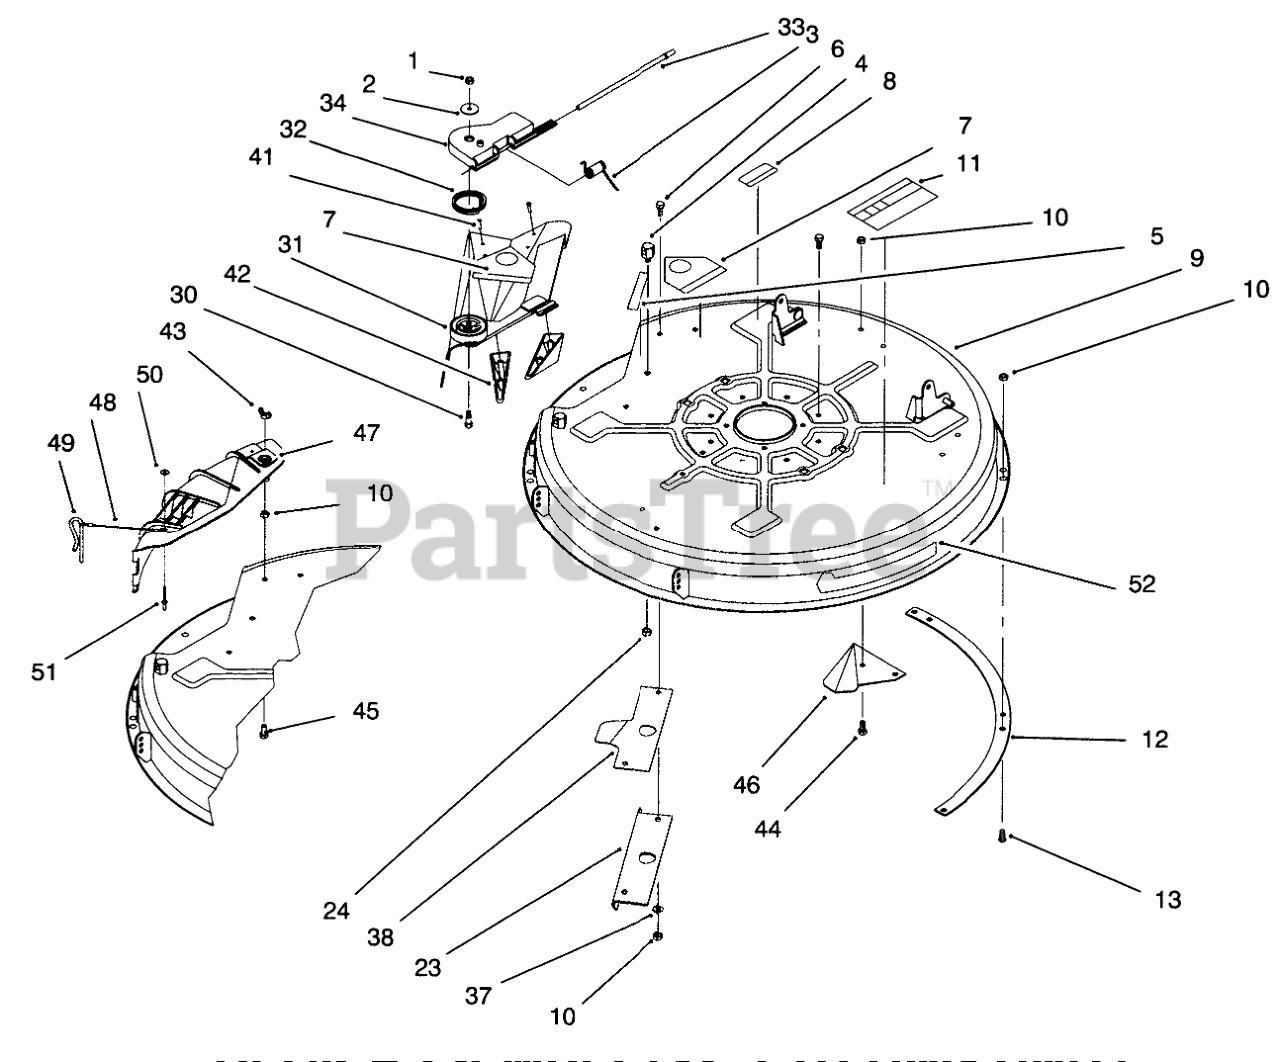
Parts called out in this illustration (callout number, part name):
1	NUT-LOCK, NI
2	WASHER-FLAT
3	SPRING-TORSION
4	POST-PIVOT
5	DECAL-DANGER, DEFLECTOR
6	SCREW-HH
7	DECAL-DANGER
8	DECAL-WARNING
9	Cutter Deck-32"
10	NUT-LOCK, NI
11	DECAL-DANGER, THROWN OBJECT
12	RING-DECK
13	SCREW-PPH
23	Baffle Deck
24	NUT-LOCK, NI
30	BOLT-SHOULDER
31	Deflector Assembly (Incl. Ref. #7)
32	SPRING-TORSION
33	ROD-HINGE, DEFLECTOR
34	PIVOT-HINGE, DEFLECTOR
37	WASHER-PLAIN
38	Ramp-Deflector
41	SCREW-PPH
42	KICKER
43	NUT-WING
44	SCREW-HH
45	SCREW-HH
46	Kicker
47	Brace-Cover, Rear
48	LANYARD
49	PIN-LOCKING, CHUTE
50	Washer-Flat (Model No. 71201 Only)
51	RIVET-BLIND
52	DECAL-RECYCLER
